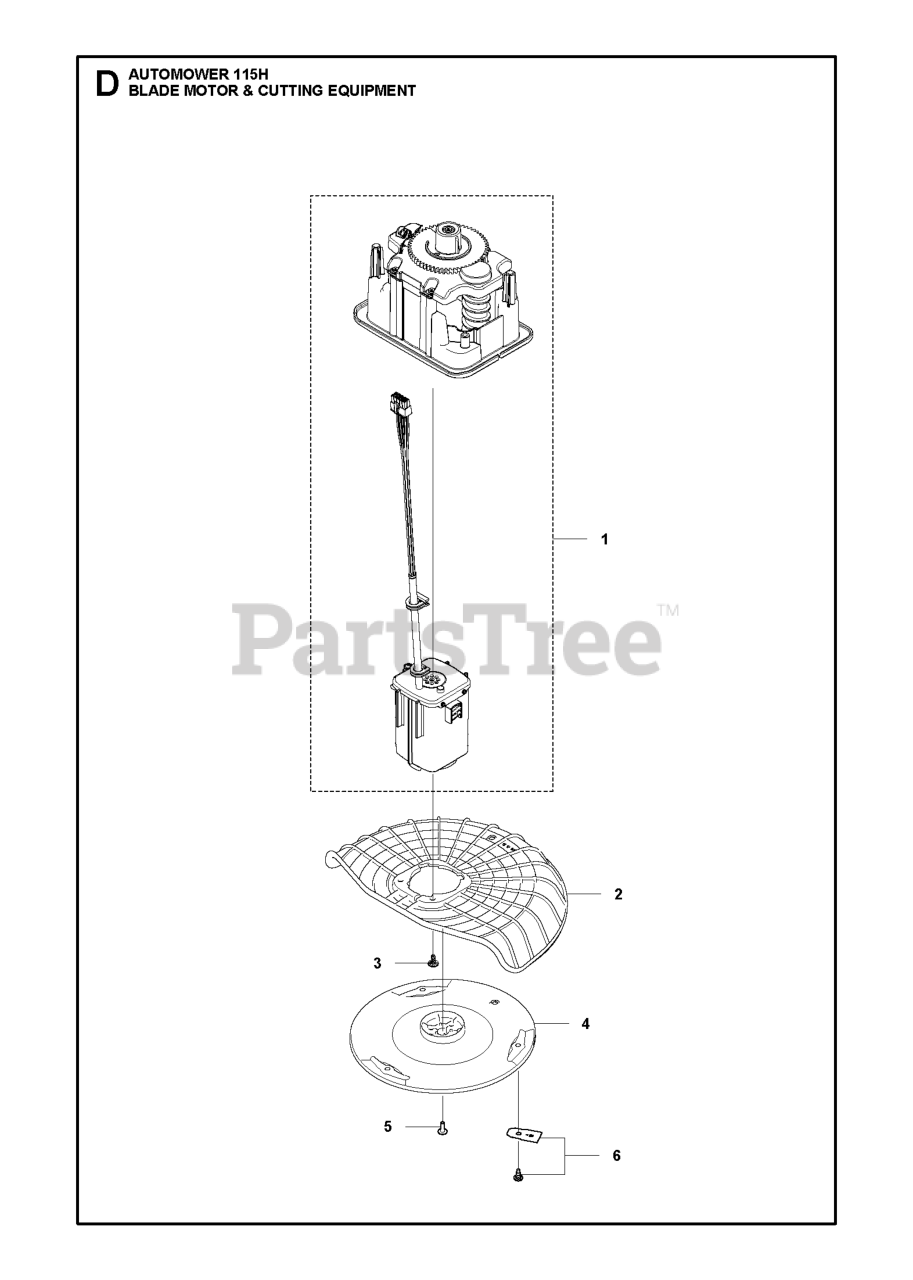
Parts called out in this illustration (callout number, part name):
1	CUTTING SYSTEM MODULE
2	GUARD
3	SCREW ITXPANT
4	CUTTING DISC
5	SCREW HEXAGON SOCKET BUTTON HE
6	HUS BLADE SET 9 PCS
